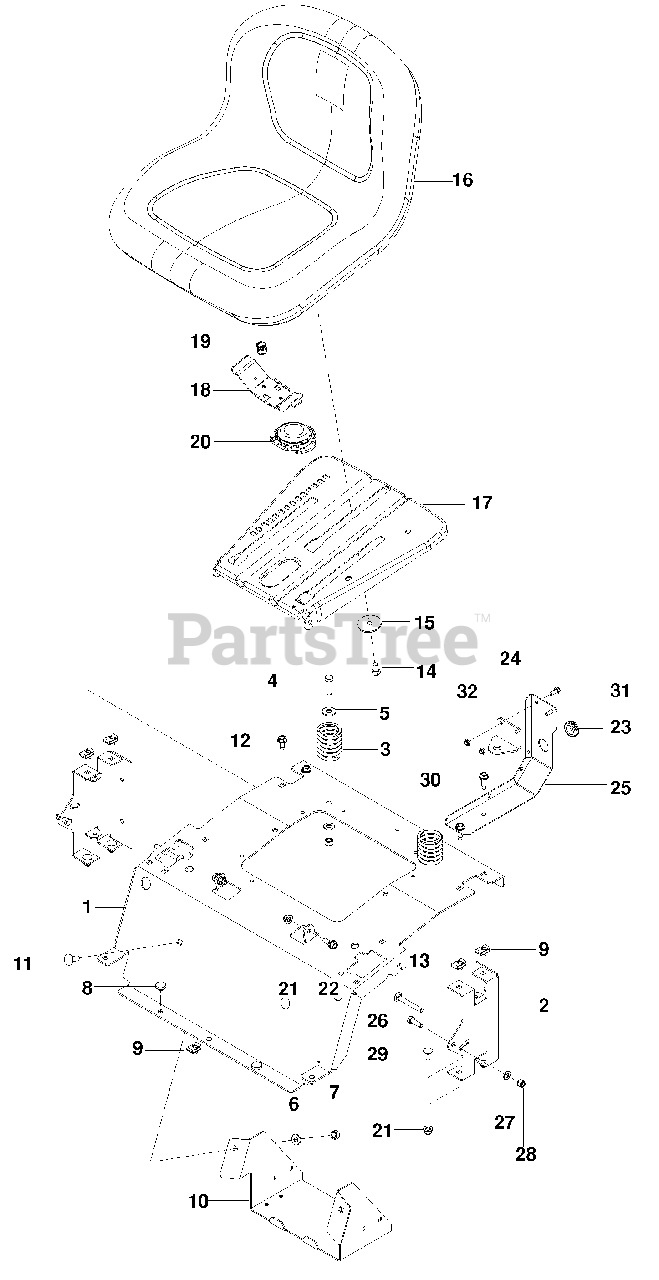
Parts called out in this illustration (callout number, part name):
1	SUPPORT, SEAT ORG
2	SUPPORT, SEAT RR BLK
3	SPRING, SEAT
4	HCS 3/8-16 x 1 1/4
5	WASHER 3/8 STD FLT
6	WASHER 3/8 SAE FLT
7	NUT 3/8-16 HEX NYLOC
8	GROMMET, BUMPER
9	RETAINER, U TYPE
10	BOX, BATTERY BLK
11	RHSNB 3/8-16 x 1
12	BOLT 5/16-18 x 3/4, THD FRM
13	RHSNB 5/16-18 x 2 1/2
14	HCS 3/8-16 x 5/8
15	WASHER 3/8 SPECIAL
16	SEAT
17	SEAT PAN
18	HANDLE, SLIDE, SEAT
19	SPRING, LATCH SEAT
20	SWITCH, SEAT
21	NUT 5/16-18 FLANGE NYLOC
22	BOLT 5/16 SHOULDER
24	BRACKET, VALVE BLK
25	MOUNT, VALVE BLK
26	HCS 5/16-18 x 1
27	WASHER 5/16 SAE FLAT
28	NUT 5/16-18 HEX NYLOC
29	RHSNB 5/16-18 x 3/4
30	BOLT 5/16-18 x 1 THD FRM
31	HCS 1/4-20 x 5/8
32	NUT 1/4-20 HEX NYLOC THIN
